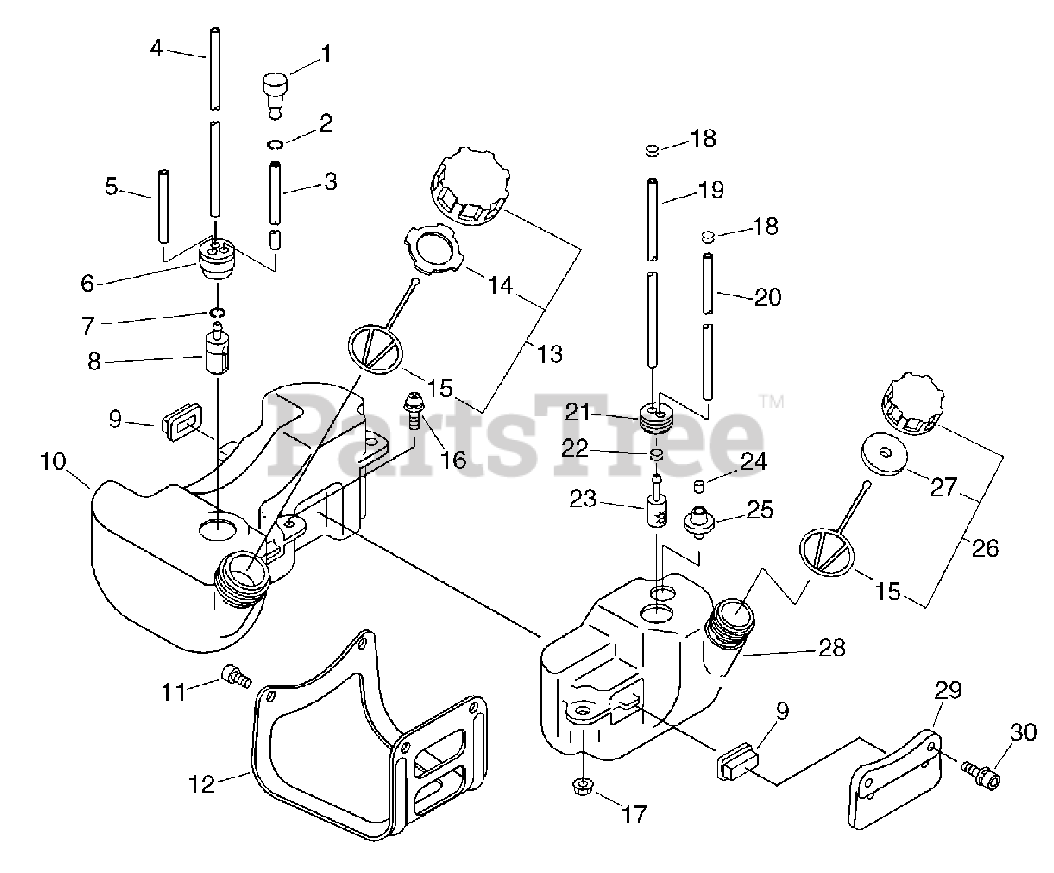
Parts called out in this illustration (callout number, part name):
1	VENT, FUEL TANK
2	CLIP - 5.5
3	PIPE - 3X5X90 -- BLACK
4	PIPE - 3X6X170 -- BLACK
5	PIPE - 3X6X60 -- CLEAR
6	GROMMET
7	CLIP - 6.5
8	FILTER, FUEL
9	CUSHION, FUEL TANK
10	TANK, FUEL
11	SCREW - 5X12
12	GUARD, FUEL TANK
13	CAP ASSY
14	GASKET, CAP
15	CONNECTOR, CAP
16	SCREW - 5X18
17	NUT - 5 -- FLANGE
19	PIPE - 2X4X180
20	PIPE - 2X4X100
23	FILTER, OIL
26	CAP ASSY
28	TANK, OIL
29	BRACKET, FUEL TANK
30	SCREW - 5X20
